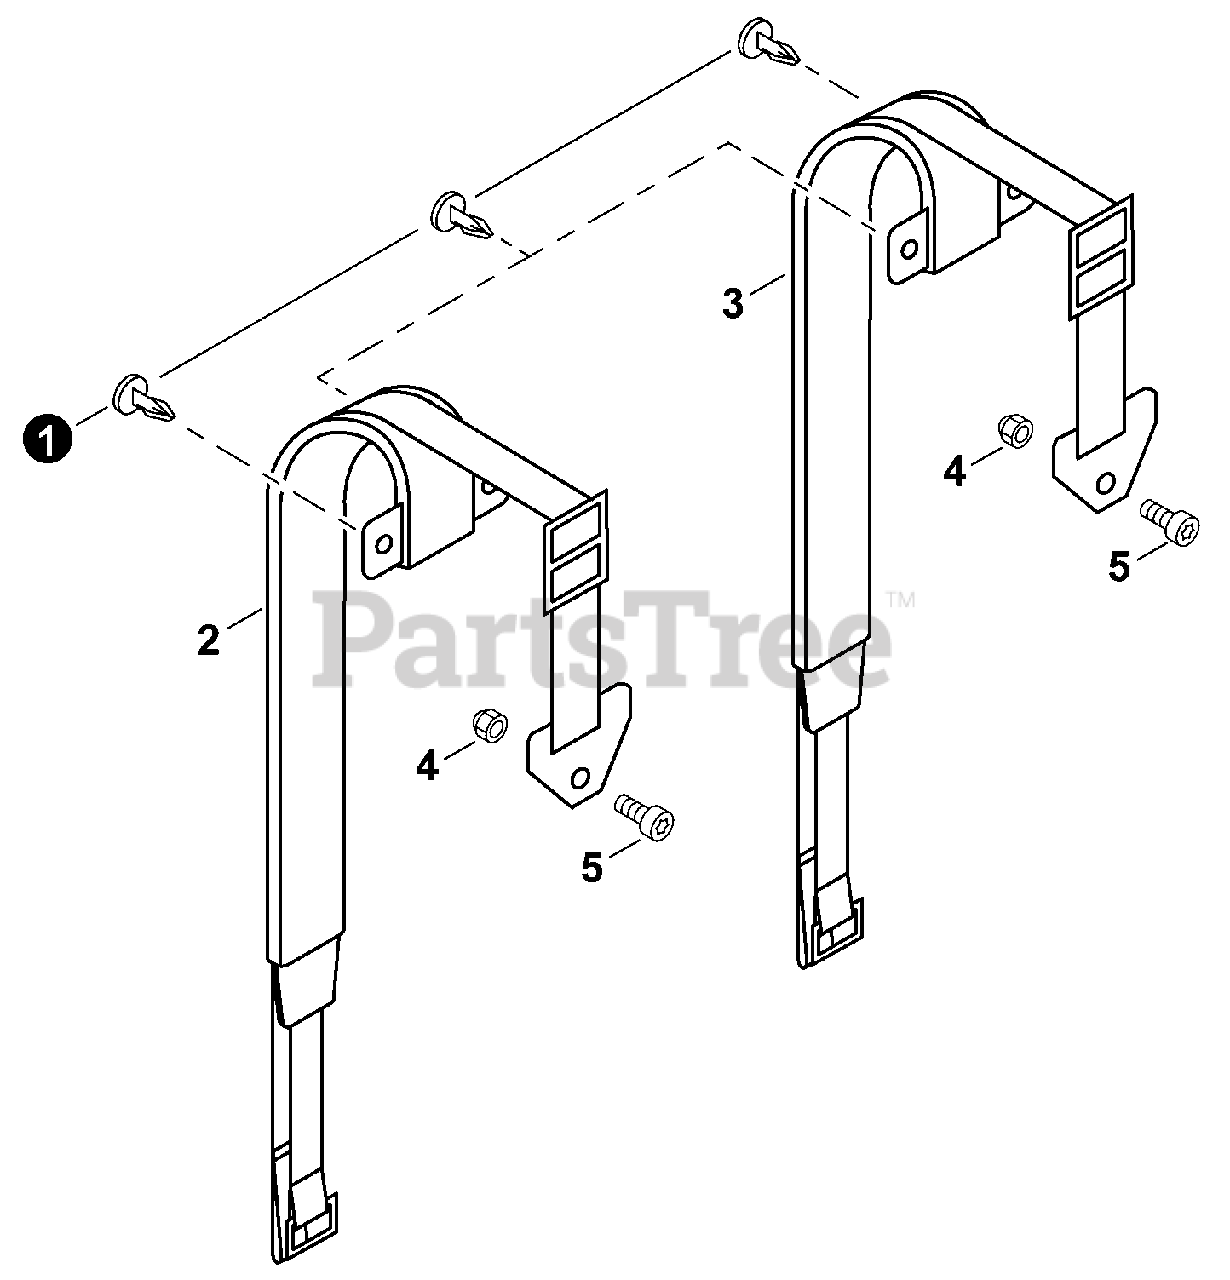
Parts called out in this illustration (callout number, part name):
2	HARNESS ASSY, LEFT
3	HARNESS ASSY, RIGHT
4	NUT, LOCK M5
5	BOLT, TORX 5×30
